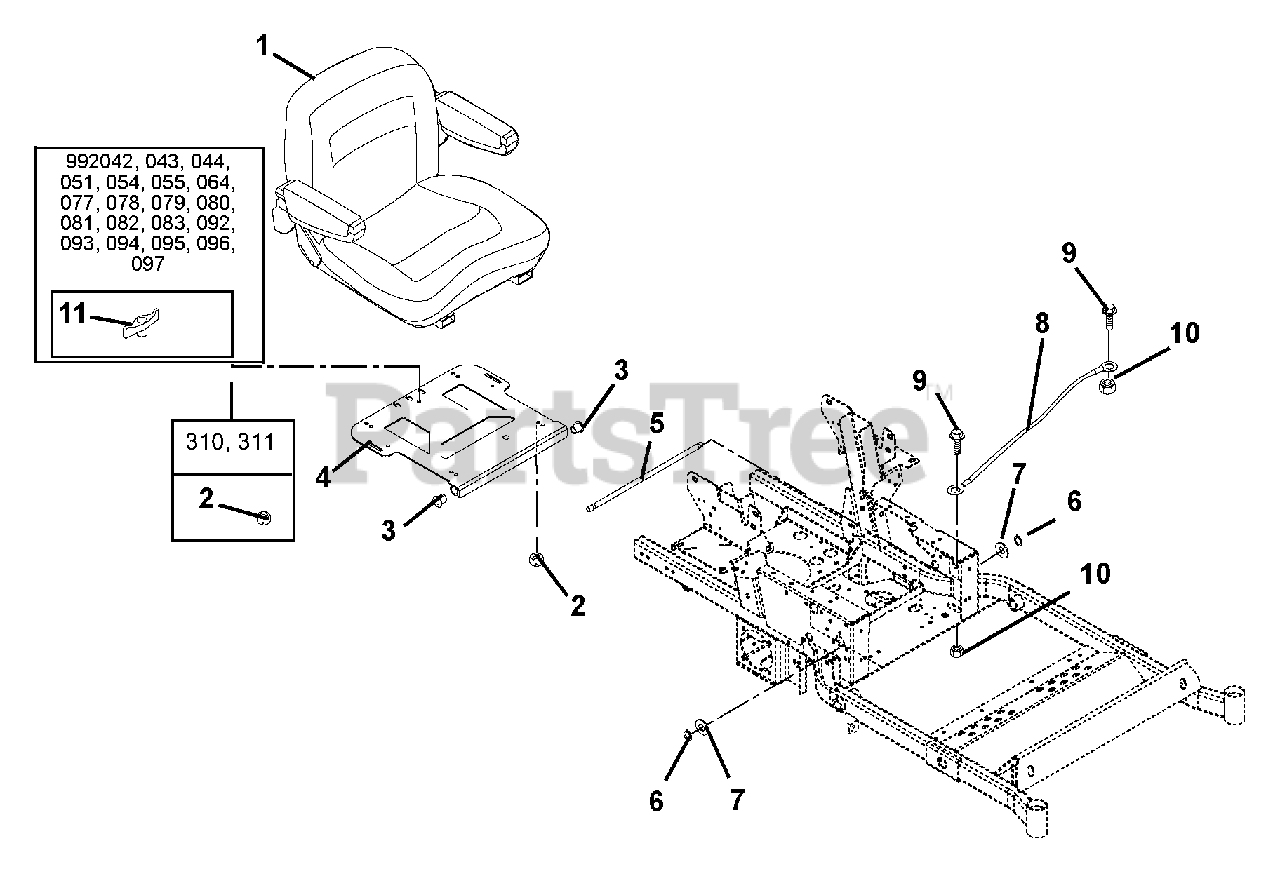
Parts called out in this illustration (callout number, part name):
2	Nut, Locking Top Flange .31-18
3	Bushing, Flange .515 x .750 x .745 x 1.00
4	Seat Pivot Mount
5	Rod, Seat Frame Pivot
6	Ring, Retaining External .500 x .050
7	Washer, Thrust .531 x 1.00 x .063
8	Cable, Hood
9	Bolt, Hex .25-20 x .75 Grade 5
10	Nut, Locking Top Flange .25-20
11	Knob, Wing .312-18
